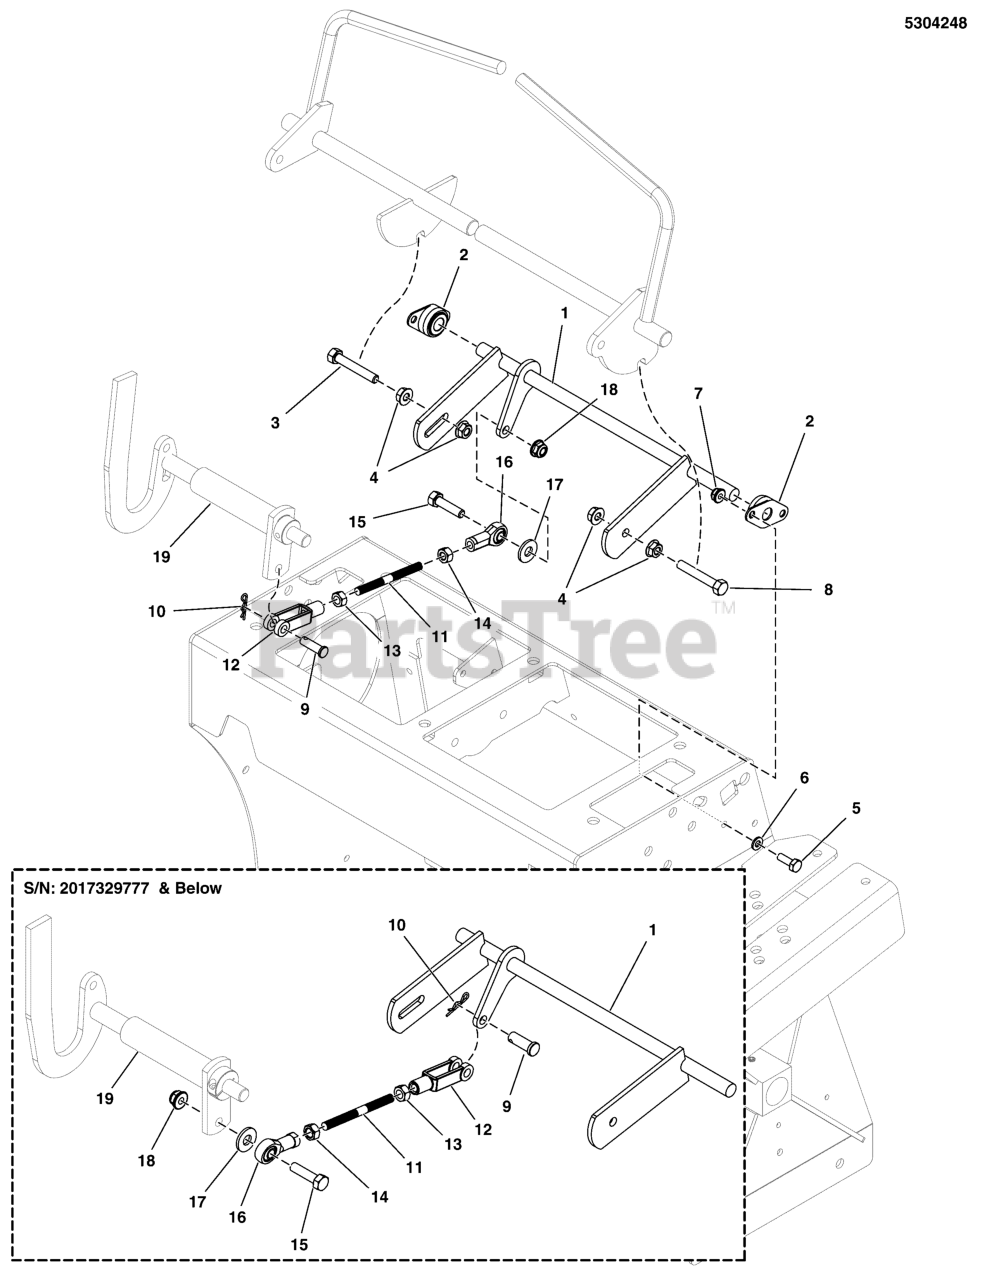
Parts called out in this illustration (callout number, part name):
1	WELD, NEUTRAL LOCK SHAFT - BLK
2	BEARING, 1/2 FLANGED, PLASTIC BALL
3	BOLT, 5/16-18 X 2 GD5 CZ
4	NUT, 5/16-18 HEX SERRATED FLANGE (SMALL)
5	BOLT, 1/4-20 X 3/4 GD5 CZ
6	WASHER, 1/4 SAE
7	NUT, 1/4-20 HEX NYLOCK FLANGE
8	BOLT, 5/16-18 X 2-1/4 GD5 CZ
9	PIN, CLEVIS, 5/16 X 1, PLATED
10	PIN, HAIR, .0585 X 1-1/8, 1/4 EYE, CZ
11	ROD, 5/16-24 X 3.25, CZ
12	CLEVIS, 5/16-24, STEEL, CLEAR ZINC
13	NUT, 5/16-24 HEX
14	NUT, 5/16-24 HEX, LH
15	BOLT, 5/16-18 X 1-1/4 GD5 CZ
16	BALL JOINT 5/16-24 LH FEMALE BRONZE RACE
17	WASHER, 5/16 USS
18	NUT, 5/16-18 HEX NYLOCK FLANGE
19	SEE PARKING BRAKE GROUP
